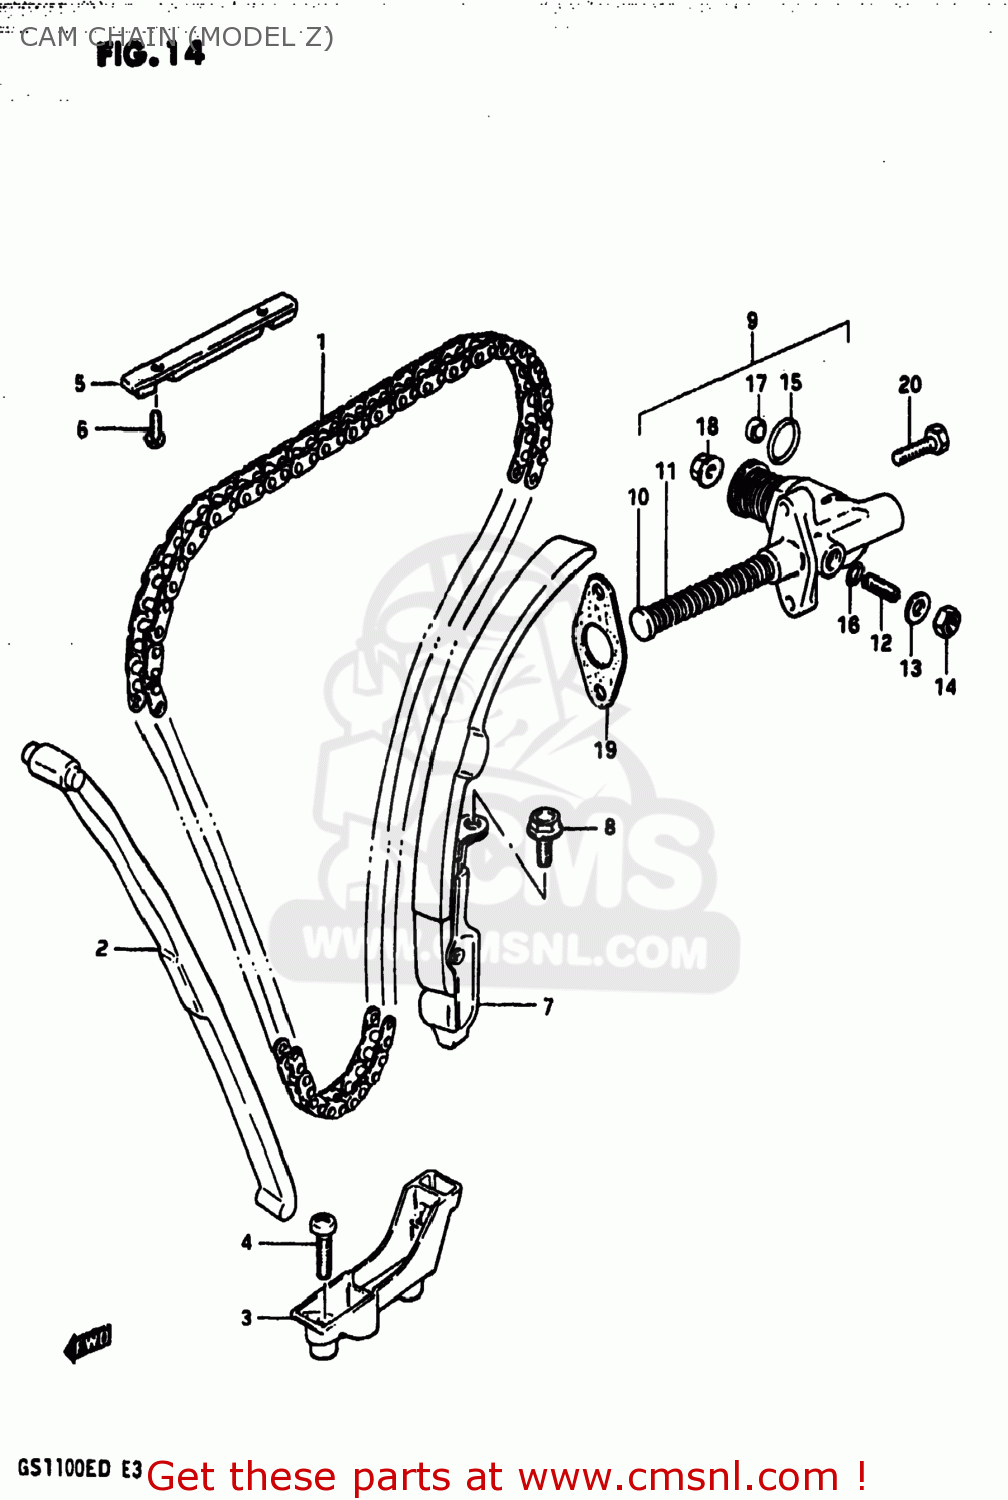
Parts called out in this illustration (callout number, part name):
1	CHAIN,CAMSHAFT DRIVE
2	GUIDE,CAM CHAIN NO.1
3	HOLDER,CAM CHAIN GUIDE
4	SCREW
5	GUIDE,CAM CHAIN
6	SCREW
7	TENSIONER,CAM CHAIN
8	BOLT
9	ADJUSTER ASSEMBLY,TENSIONER
10	ROD,PUSH
11	SPRING
12	SCREW
13	WASHER
14	NUT
15	O-RING
16	O-RING
17	OIL SEAL
18	NUT
19	GASKET,TENSIONER ADJUSTER (MCA)
20	SCREW (6X25)
